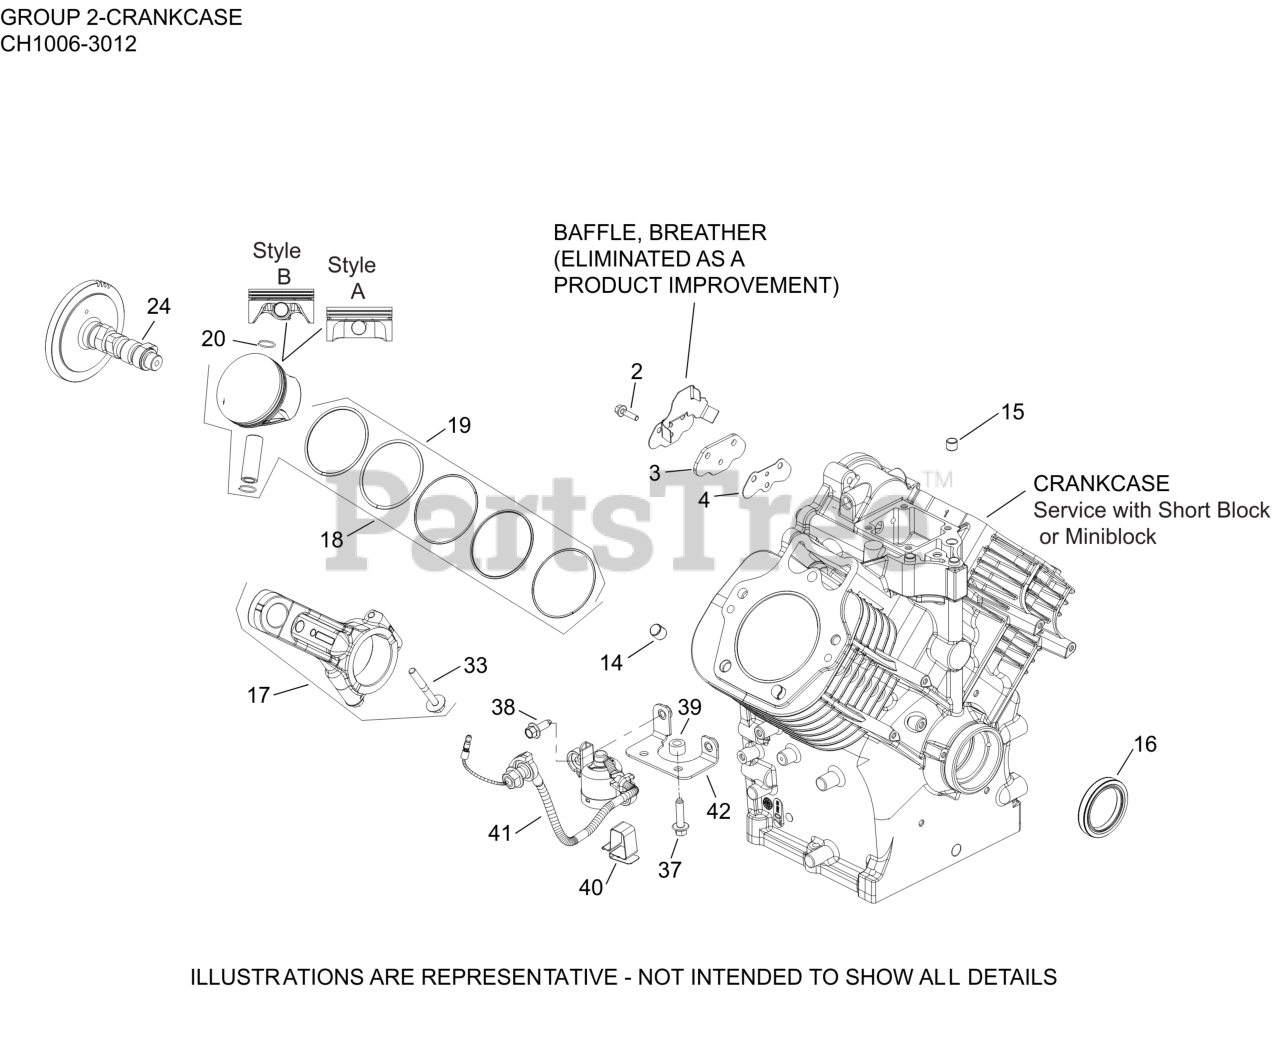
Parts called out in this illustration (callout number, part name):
2	SCREW, HEAVY HEX FLANGE
3	KIT, COVER, LIFTER FEED
4	GASKET, LIFTER FEED COVER
14	PIN, LOCATING
16	SEAL, OIL (RIGHT-HAND HELIX, FWE)
17	CONNECTING ROD ASSEMBLY
18	KIT, PISTON (STD)
18	KIT, PISTON (0.25 OS)
18	KIT, PISTON (0.50 OS)
19	RING, SET PISTON (STD) "STYLE B ONLY"
20	RETAINER, PISTON PIN
24	KIT, CAMSHAFT
33	KIT, ROD BOLTS
37	SCREW, FLG M6X1.0X25
38	SCREW, HEX FLANGE (M6 W/DOG POINT)
40	CLIP, BLOWER HOUSING
41	SWITCH, OIL SENSOR ASSEMBLY
42	BRACKET, SWITCH OIL SENSOR
